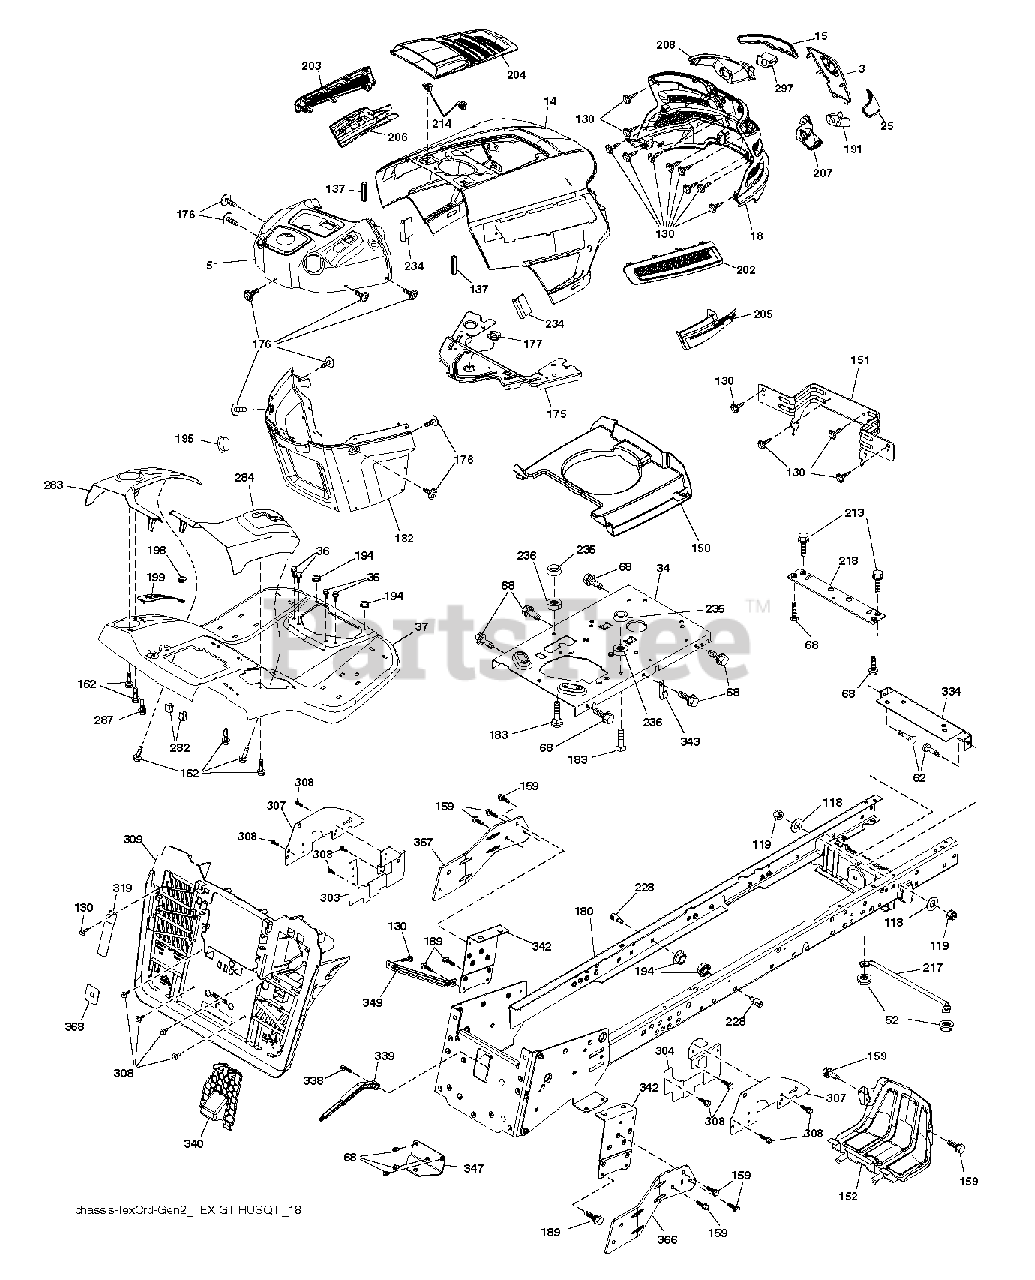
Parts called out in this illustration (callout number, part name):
3	APPLIQUE.SUBASM.GT.HUSQ.II
5	DASH.GT.HUSQTX.SM.M.RS.CH.498
14	HOOD.ASM.HUSQVARNA.GT.TEX.ORAN
15	LENS.HEADLIGHT.LH.GTII.2011
18	GRILLE.SUBSTRATE.2011.
25	LENS.HEADLIGHT.RH.GTII.2011
34	PLATE.ENGINE.10GA.CRD.GENII
36	SCREW 5/16"
37	FENDER.TEX.SRD.CRD.BASE
52	LOCKNUT
62	BOLT D
68	SCREW LT
118	WASHER
130	SCREW.#10 X 0.750.BOS
137	BUMPER DASH
150	AIR.DUCT.GTV.BLACK
151	BRACKET.PIVOT.HOOD.GT.HUSQ.II
152	SHIELD.BROWNING.PNT.GT.V2
159	SCREW, 3/8-16X3/4
162	SCREW.HI-LO.CONSOLE
175	PLATE.CROSSMEMBER.HUSQ
176	SCREW.#10-24X5/8.RN.QU
177	BUSHING, STEERING
180	WELDMENT.CHASSIS.TEX.CRD.GEN.2
182	DASH LOWER.HUSQ.PRED NO CRUISE
183	BOLT.5/16-18X1-1/4 FULL THD
189	SCREW
191	INSERT.REFLECTIVE.RH.HUSQ.GTII
194	NUT LOCK HEX FLANGE 5/16-18
195	PLUG.HOLE.DASH.LOWER.12V.BLK
198	INDICATOR.DECK.LIFT.RED
199	PLATE DECK LIFT
202	VENT.SIDE.RH.GT.HUSQ.II.
203	VENT.SIDE.LH.GT.HUSQ.II.498
204	VENT.TOP.ASM.HUSQ.GT2
205	SIDE.TRIM.RH.GT.HUSQ.II
206	SIDE.TRIM.LH.GT.HUSQ.II.GRAY
207	BEZEL LIGHT.RH.GT.II.MYLAR
208	BEZEL LIGHT.LH.GT.II.MYLAR
213	BOLT
214	CLIP.RETAINER.TINNER.
217	ROD.PIVOT.HOOD
218	X-PIECE.HOOD.STOP.NON/
228	STUD.FASTNER.W/ANTI-ROTATE
234	BUMPER.HOOD.TEX.HUSQVARNA
235	SPACER FENDER
236	NUT.CENTERLOCK.5/16-
282	CLIP.RETAINER.CONSOLE.LT.HUSQ
283	CONSOLE.DECKLIFT.CRDII.498
284	CONSOLE.PEDAL.HYDRO
287	SCREW 1/4X20
297	INSERT.REFLECTIVE.LH.HUSQ.GTII
303	SHIELD.LWR.LH.LT.30"CRDSRD.PNT
304	SHIELD.LWR.RH.LT30DECK.PNT.BLK
307	SHIELD.UPPER.CRD.SRD.ISO
308	BOLT, 5/16-18 X 1 3/4
309	BACKPLATE.ASM.CRDII.ANTIROTAT
319	LEVER.BAG.CRDII.ANTIROTATION
334	BRACKET.ENGINE
338	BOLT BOLT SHOULDER
339	LEVER LEVER BAGGER
340	BATTERY.DOOR.TEX.CRD.GEN.2,1
342	SUPPORT SUPPORT FENDER
343	CLIP CLIP
347	HITCH TOW
349	BRACKET.SUPPORT.LRVB/CRD
366	BRACKET.RH.FRONT.BAGGER.BLACK
367	BRACKET.LH.FRONT.BAGGER.BLACK
368	FULL.LEVER.BAGGER.TEX.CRD
